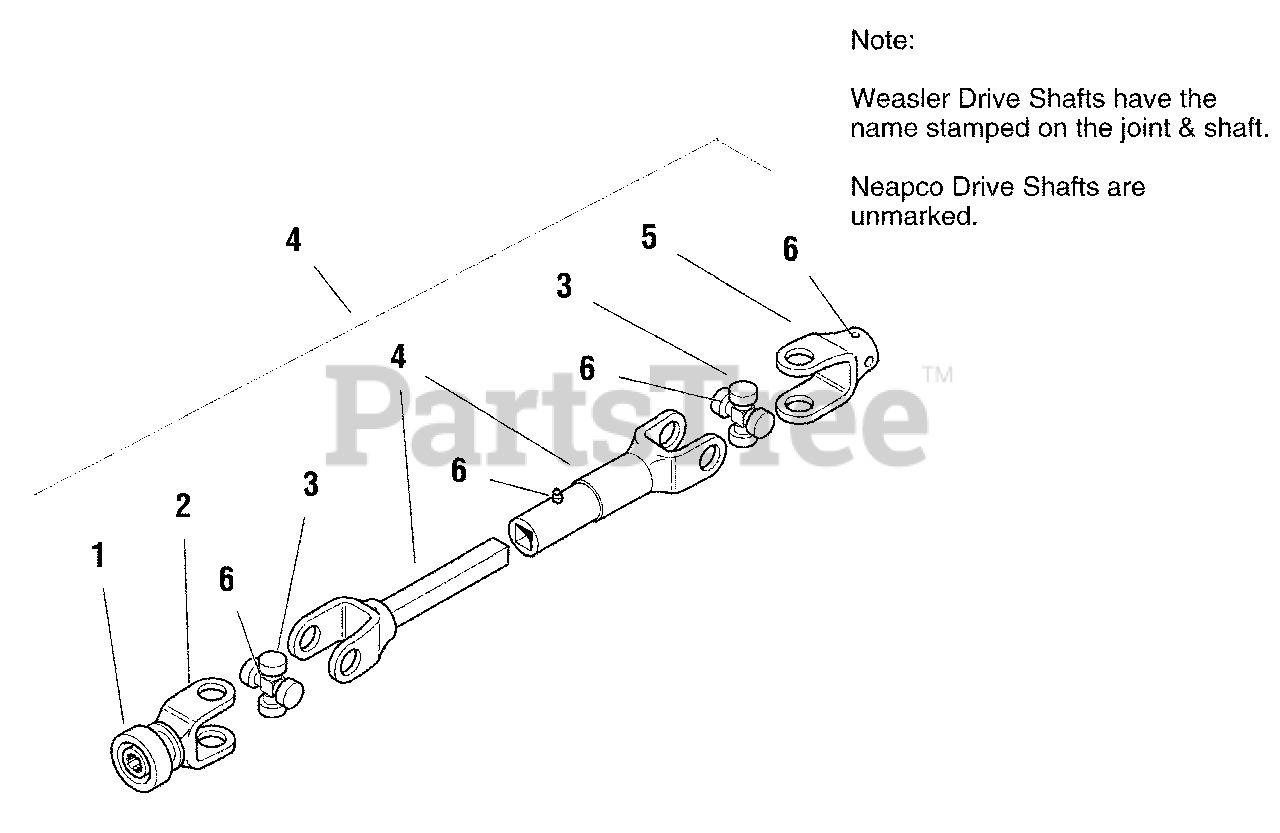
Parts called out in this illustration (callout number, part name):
1	SPRING LOCK REPAIR KIT (Neapco)
1	SPRING LOCK REPAIR KIT (Weasler)
2	* YOKE ASSEMBLY (Neapco)
2	YOKE ASSEMBLY (Weasler)
3	CROSS & BEARING KIT (Neapco)
3	CROSS & BEARING KIT (Weasler)
4	* YOKE & TUBE ASSEMBLY
4	DRIVE SHAFT, Complete
5	YOKE (Neapco)
5	YOKE (Weasler)
6	** FITTING, Grease, w/ Check Ball
